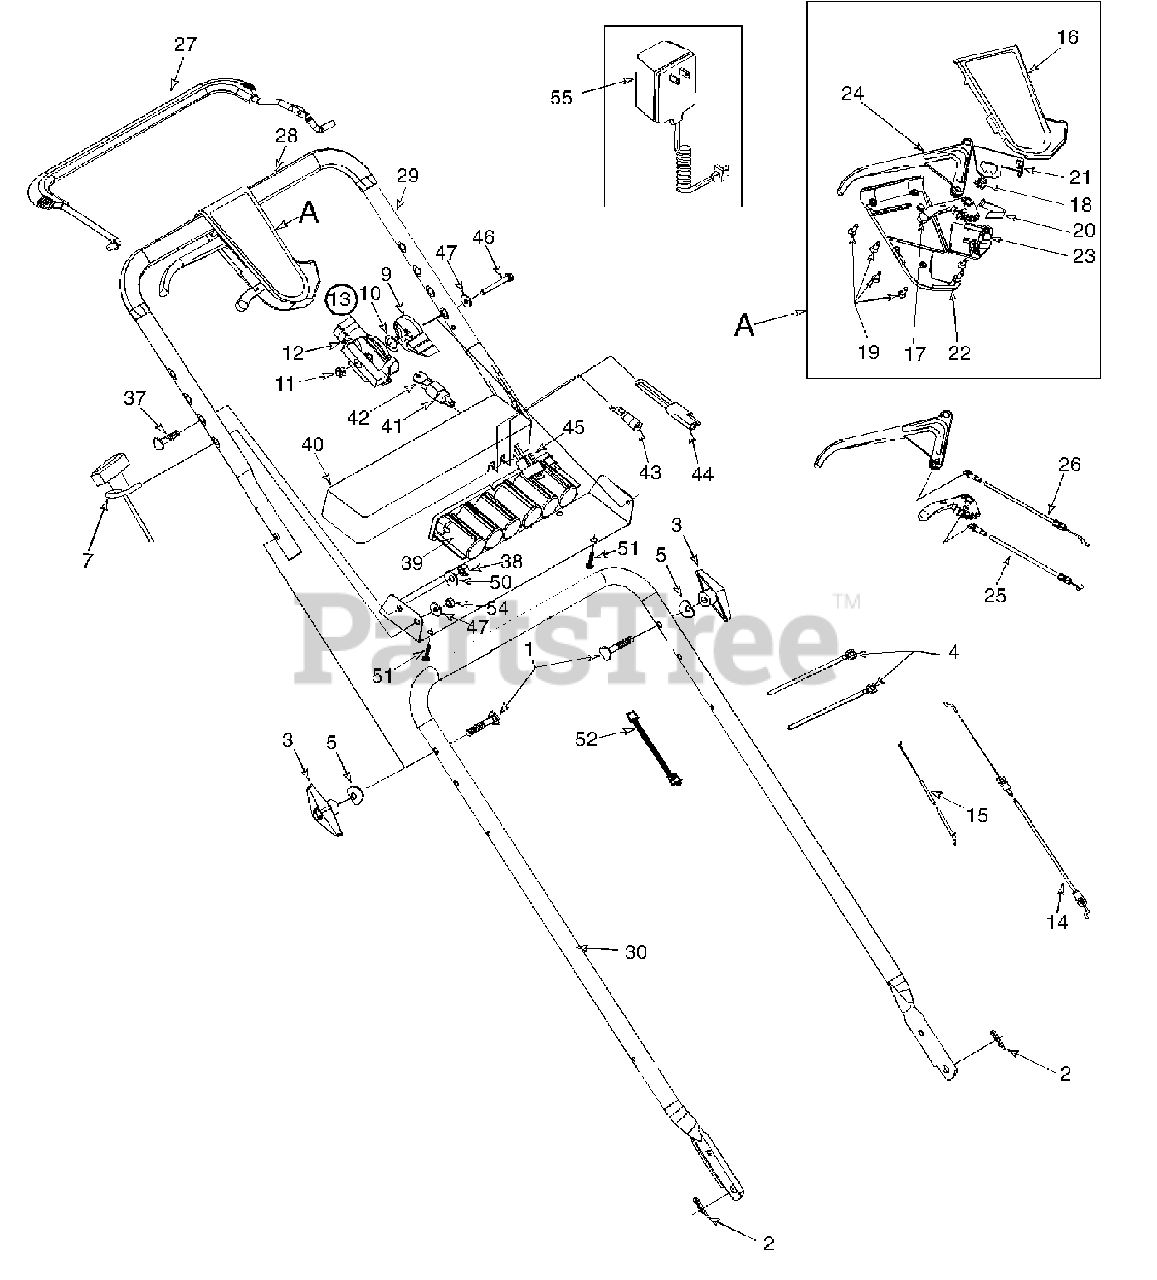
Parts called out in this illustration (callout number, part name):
1	Bolt Cur. Carr. 5/16-18 x 2.0
2	Cotter Pin .072 x 1.12 Lg.
3	Knob Assembly
4	Strap 4.3 Lg.
5	Wash. Sad. .320 ID x .830 OD
9	Throttle Lever
10	Spring Wash. Curved
11	Nut 1/4-20 Top locknut Insert
12	Housing, Throttle
13	Throttle Control
14	Control Cable 47" Lg.
15	Cable Throttle 60" Lg.
16	Upper Control Housing
17	6 Speed Shift Lever
18	Gear Insert
19	C Sunk Tap Screw #10 x .75 L
20	Shift Lever Spring
21	6 Spd. Rack Cable Brkt.
22	Lower Control Housing
23	Cable Mounting Cap
24	Control Lever
25	6 Spd. Cable
26	S.P. Cable
28	Foam Grip
37	Cur. Carr. Bolt 5/16-18 x 1" Lg.
38	Hex Nut 5/16-18 Thd.
39	Battery Pack - 12 Volt
41	Ignition Switch
42	Ignition Key
43	Fuse Holder
44	Plug
45	Wire Harness
46	Hex Bolt 1/4-20 x 2" Lg.
47	Bell Wash 1/4" I.D.
51	Truss Mch. Tap Scr. 1" Lg.
52	Harness Ext.
54	Hex Nut 1/4-20
55	Battery Charger
